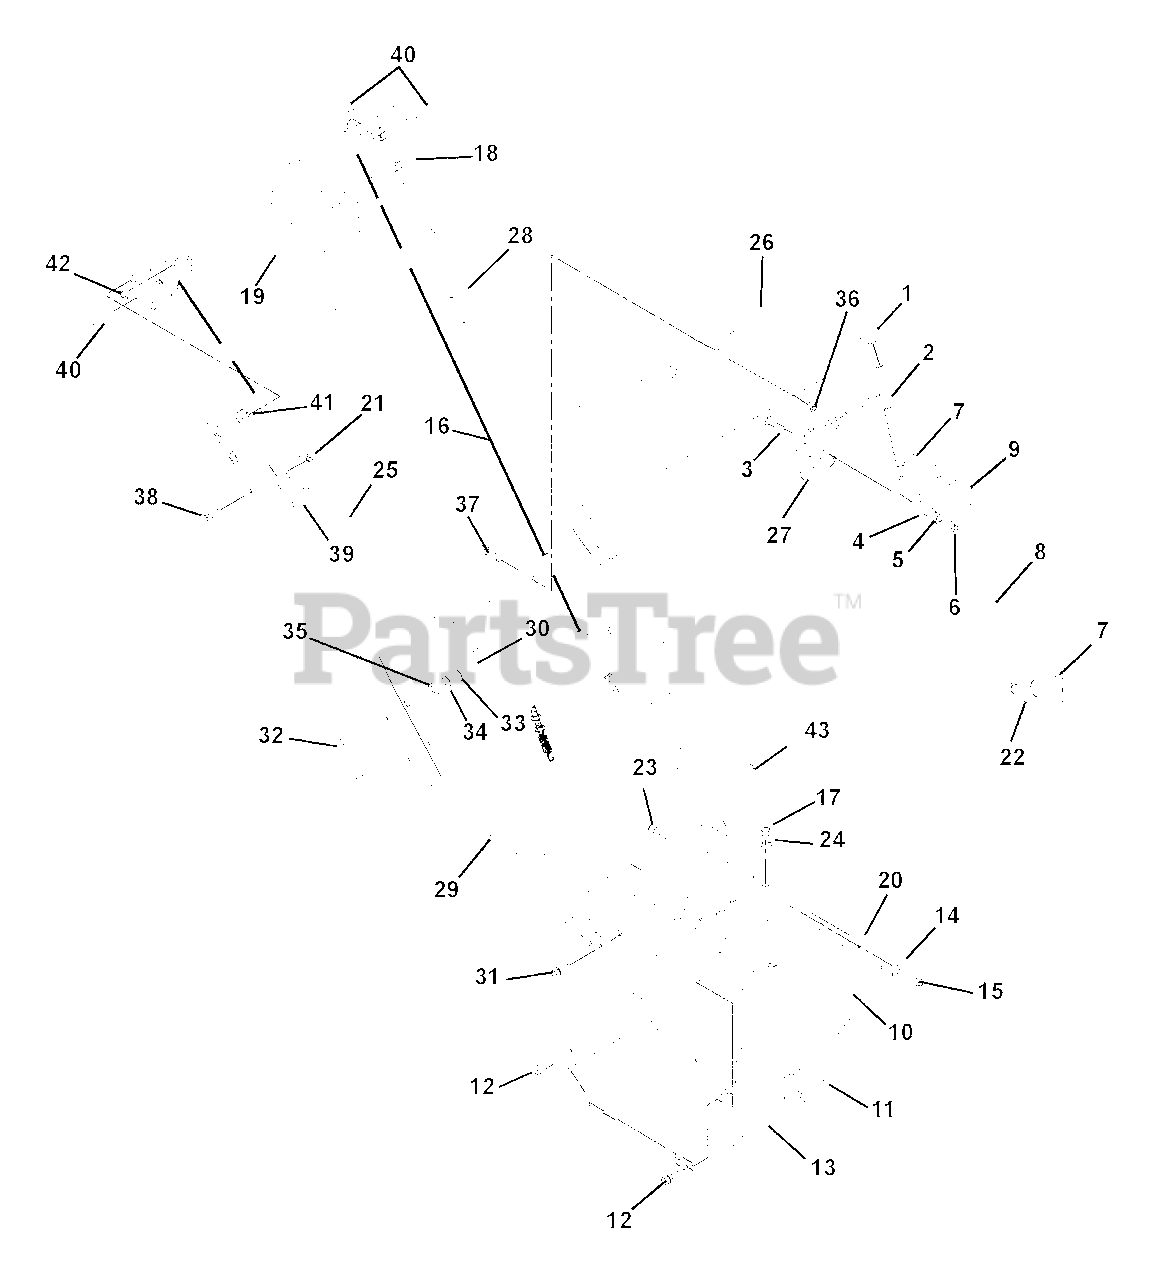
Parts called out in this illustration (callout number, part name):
1	KNOB,BALL -BLACK 1.47" .375-16
2	WMT, SHIFT LEVER
3	@BLT-HEX .38-16X2.00 GR5 YWZC
4	SG-COMP .125X.781X1.250
5	@WSHR-FL-STL.438X1.00X.083 YWZ
6	@NUT-LK-CTR .38-16 YWZC
7	PIN-HAIR INT .08X.18X1.18 YWZC
8	ROD, SHIFT
9	PIVOT, ROD (TRUNNION ) .50
10	FRAME, COMPACT SNOW
11	STRAP, ENGINE BOLT-WELDMENT
12	@SCR-TAP .25-20X.37 HWH YWZ TR
13	COVER BOTTOM
14	@WSHR-FL-STL.38X.875X.083 YWZC
15	@NUT-LK-CTR .31-18 YWZC
16	CABLE, TRACTION
17	@NUT-HEX .31-18 YWZC
18	BAIL, TRACTION
19	BAIL, AUGER
20	BELT FINGER LOWER
21	@NUT-LK-CTR .25-20 YWZC
22	@WSHR-FL-STL.531X1.06X.095YWZC
23	@BLT-RHDSSQNK .31-18X.75 G5YZ
24	WSHR-LK .312X.097 HVY YWZC
25	CABLE, AUGER
26	CONTROL PANEL W/DECAL
27	BRACKET, LEVER SHIFTER
28	HANDLEBAR W/DECAL
29	HANDLEBAR, LOWER
30	KNOB - WING .312-18 UNC
31	BLT SERHFWH .31-18X.62 GR5YWZC
32	J BOLT .31-18
33	@WSHR-FL-STL.38X.875X.083 YWZC
34	WSHR-LK .312X.097 HVY YWZC
35	WASHER,SADDLE-.320 X.937 X.062
36	@NUT-LK-TOP-FLG .25-20 YWZC
37	@BLT-HEX .25-20X1.50 GR5 YWZC
38	BLT-RDHDXLSQNK.25-20X1.25 G5ZC
39	ANCHOR, CABLE
40	CAP, VINYL, .25 ID
41	BSHG-FLG .325X.444X.440X.560
42	RG-RTNG-EXT .250X.010
43	RVT-POP .187X.45 DOME SS FBF64
